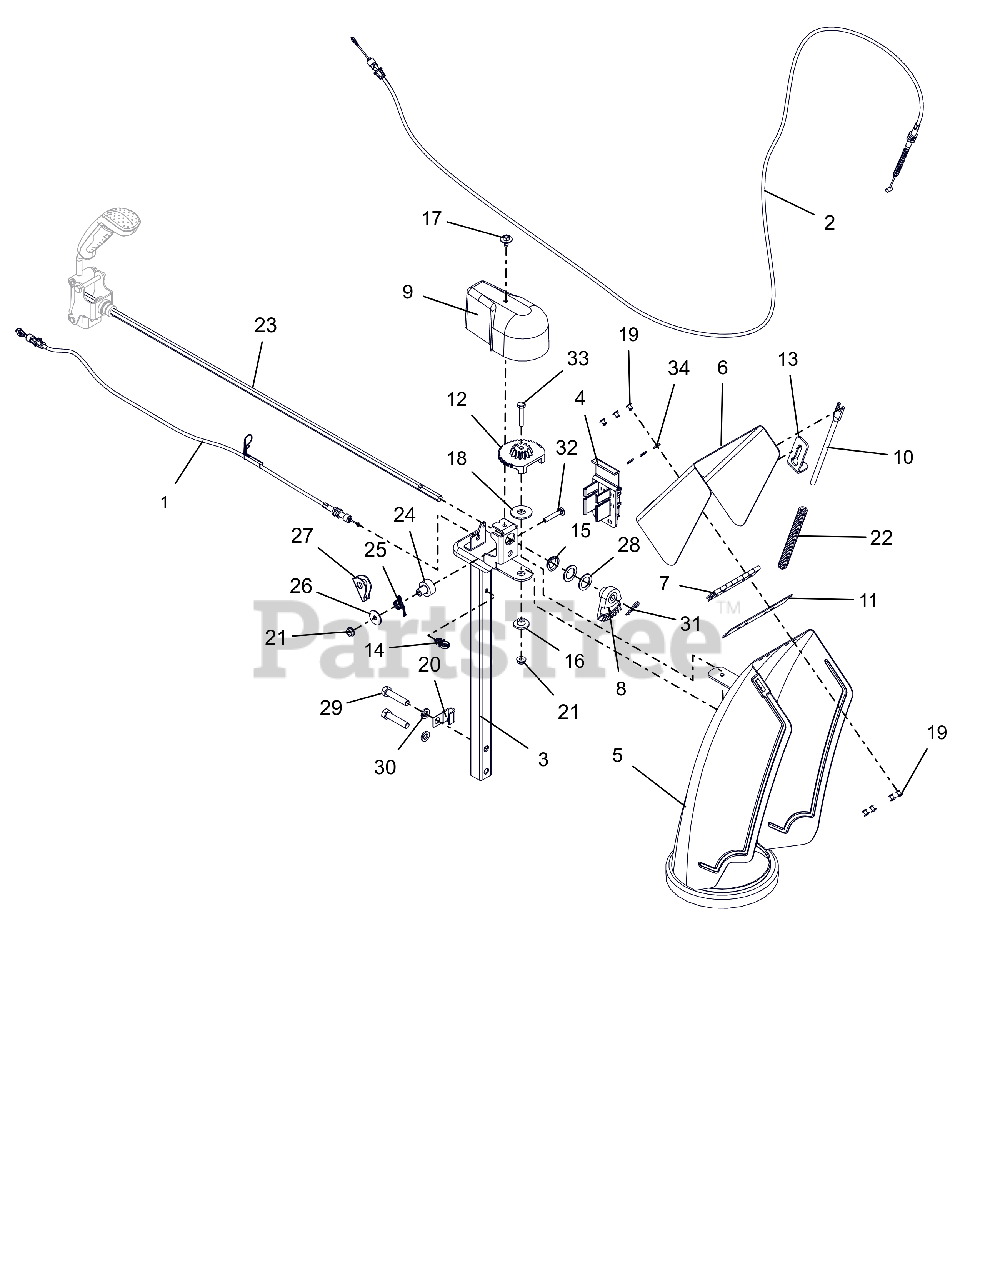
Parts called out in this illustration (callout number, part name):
1	CABLE, CHUTE LOCK, PRO
2	CABLE, DEFLECTOR - DELUXE
3	PEDESTAL, CHUTE - QUICK STICK
4	HOLDER W LARGE SHEAR BOLT /NUT
5	CHUTE,DISCHARGE,NOTCHED,QT
6	CAP, LARGE REMOTE W/DECAL
8	GEAR, CHUTE-ACTUATION
9	COVER, CHUTE GEAR
10	ROD, DEFLECTOR CAP
11	CAP SEAL 5.50
12	GEAR, CHUTE
13	BRACKET, ANCHOR-CHUTE CABLE
14	CLIP, CABLE GUIDE
15	BUSHING, POLYLINER-.75 SNAPIN
16	BSHG-FLG .265X.477X.375X1.00
17	SCR, TAP .25-20X.50 LG HWH ZCC
18	WSHR-FLT-NYL .515X1.375X.093
19	RVT-POP .187 YZ
20	J-CLAMP
21	NUT-LK-CTR-FLG .25-20 ZC120
22	SG-COMP .08X.40X6.50 14#/IN
23	ROD, HEX - CHUTE ROTATION
24	BUSHING, LOCK ARM
25	SG-TORS
26	WSHR,FLT .281X1.000X.063 ZCC
27	ARM, LOCKING
28	WSHR, FLT .754X1.125X.062 ZCC
29	BLT, HEX .38-16X1.75 G5 ZCC
30	WSHR,LK-REG .375X.094 ZCC
31	PIN, HAIR #213 .08X1.19 ZCC
32	BLT, RHSN .25-20X1.50 G5 ZCC
33	BLT, HEX .25-20X1.50 G5 ZCC
34	WSHR,FLT .196X.500X.066 ZCC
